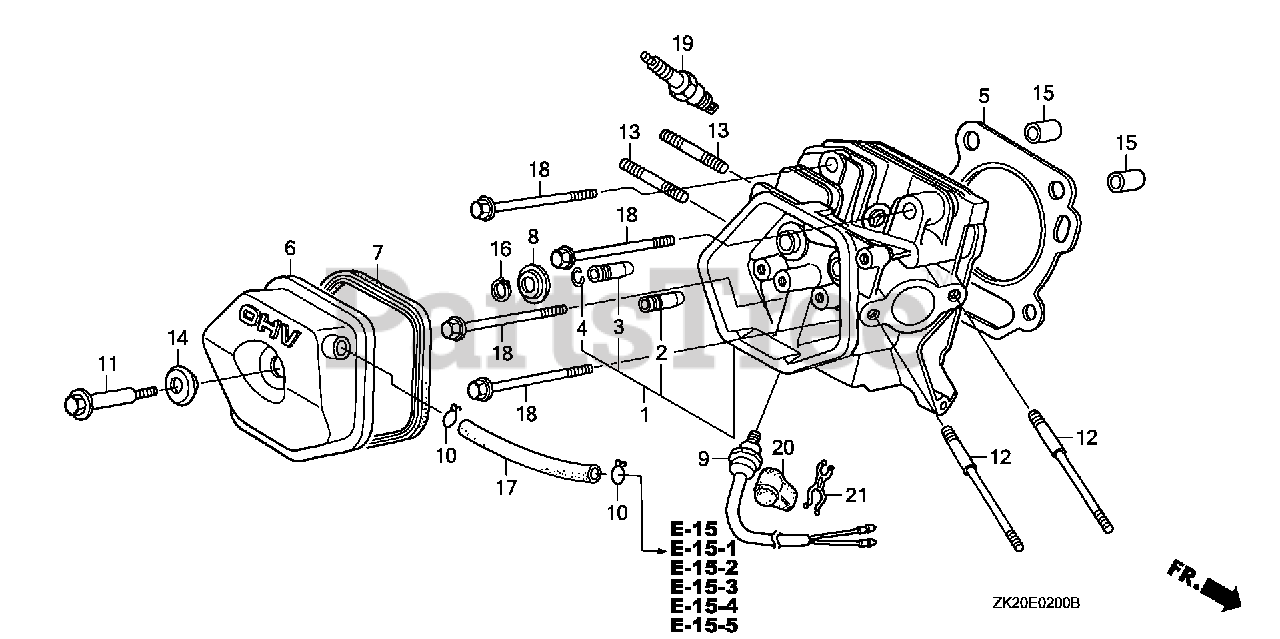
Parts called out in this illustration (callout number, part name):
1	CYLINDER HEAD
2	GUIDE, VALVE (OVER SIZE)
3	GUIDE, EX. VALVE (OVER SIZE)
4	CLIP, VALVE GUIDE
5	GASKET, CYLINDER HEAD
6	COVER, HEAD
7	GASKET, HEAD COVER
8	SEAT, VALVE SPRING
11	BOLT, HEAD COVER
12	BOLT, STUD (8X123)
13	BOLT, STUD (8X47)
13	BOLT, STUD (8X32)
14	WASHER, HEAD COVER
15	PIN, DOWEL (12X20)
17	BULK HOSE, VACUUM (11X1000) (11X100)
17	BULK HOSE, VACUUM (11X1000) (11X105)
18	BOLT, FLANGE (10X80)
19	SPARK PLUG (BPR5ES) (NGK)
19	SPARK PLUG (W16EPR-U) (DENSO)
19	SPARK PLUG (BPR6ES) (NGK)
19	SPARK PLUG (W20EPR-U) (DENSO)
